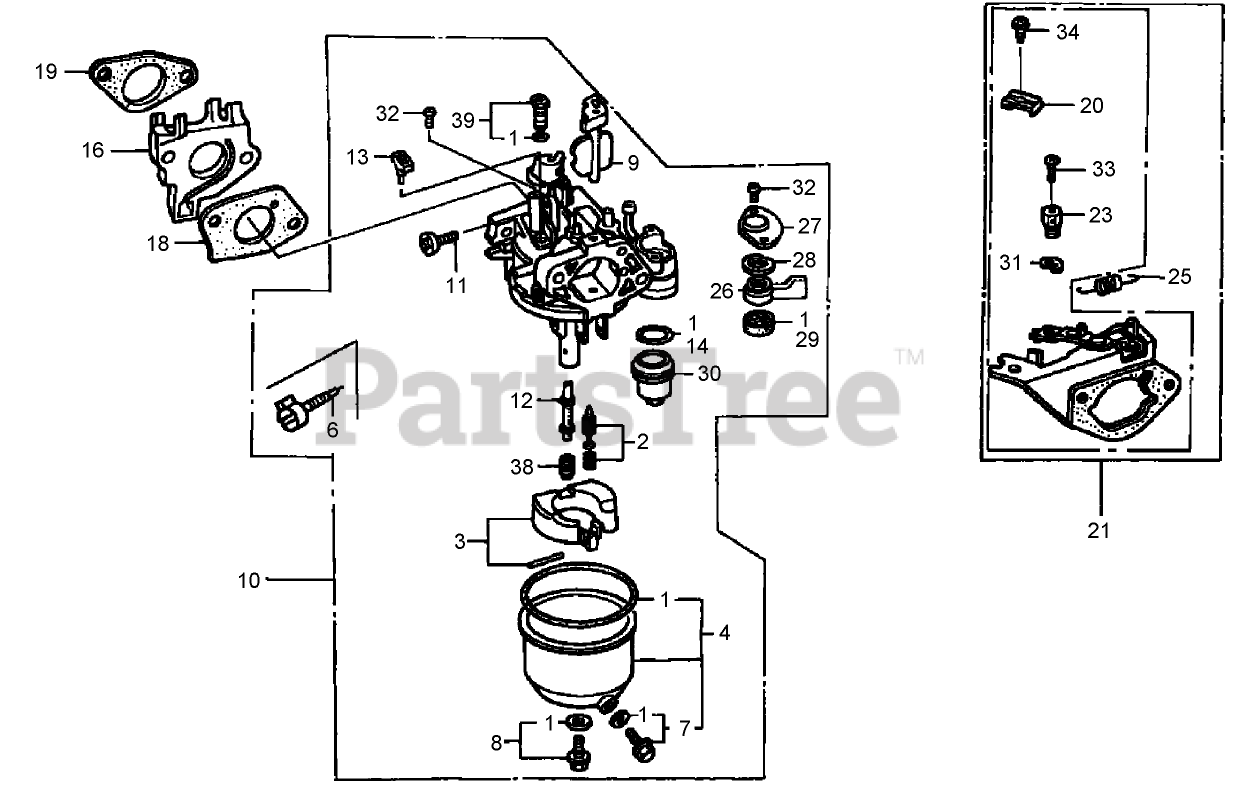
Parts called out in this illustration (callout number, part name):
1	GASKET SET
2	VALVE SET-FLOAT
3	FLOAT SET
4	CHAMBER SET-FLOAT
6	PILOT SCREW SET
7	DRAIN SCREW SET
8	SCREW SET
9	CHOKE SET
10	CARBURETOR ASM (BE85B)
11	SCREW- STOP, THROTTLE
12	NOZZLE-MAIN
13	COLLAR-SET
14	GASKET-FUEL STRAINER
16	INSULATOR-CARBURETOR
18	GASKET-CARBURETOR
19	GASKET-INSULATOR
20	Holder-Cable
21	STAY ASM-CHOKE (REMOTE)
23	HOLDER-WIRE
25	SPRING-RETURN
26	LEVER-PETCOCK
27	PLATE-SETTING, LEVER
28	SPRING-LEVER, PETCOCK
29	GASKET-PETCOCK
30	CUP-FUEL STRAINER
31	CIRCLIP (5MM)
32	SCREW-PAN (3X6)
33	SCREW-PAN (4X6)
34	SCREW-WASHER
38	JET-MAIN (No. 88)
38	JET-MAIN (No. 90)
38	JET-MAIN (No. 92)
39	JET SET, PILOT (#45)
